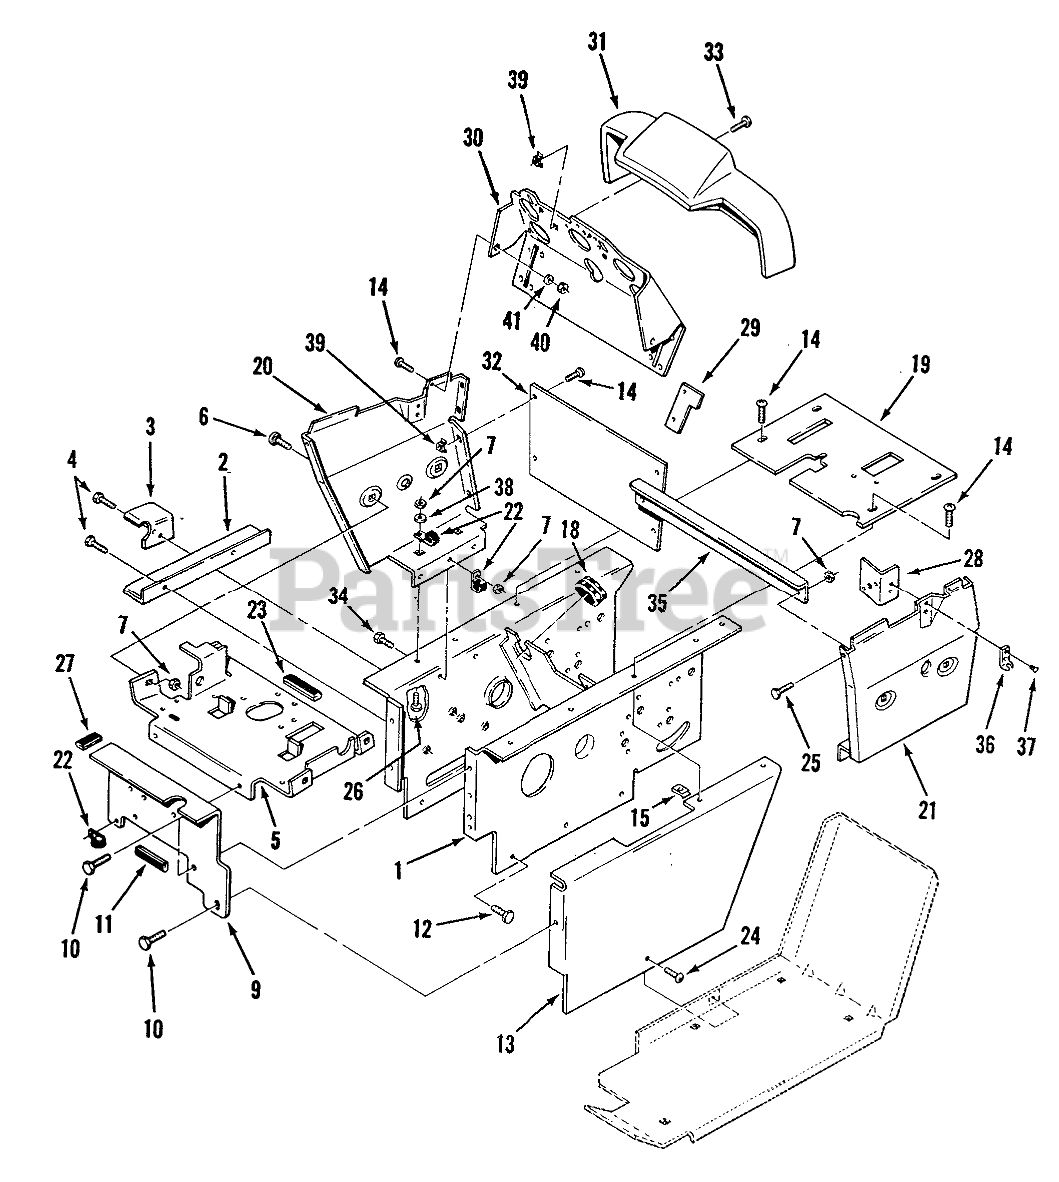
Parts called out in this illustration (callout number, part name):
1	Hoodstand
2	ANGLE-BELT GUARD B
3	BRCKET-BLT SUTB
4	SCREW
5	SUPPORT-BATTERY B
6	Bolt
7	Nut
9	PLATE-FRT HOODSTA B
10	SCREW
11	EDGE TRIM 2" 102896
12	SCREW
13	COVER-L.H. R
14	SCREW-PPH
18	GROMMET
19	Shift Cover Plate 520-H
20	Panel-RH
21	PANEL-SIDE LS B
22	CLIP
23	EDGE TRIM 5" OF 102896
24	Screw
24	WASHER 5/16 SAE
25	H H C S
26	CARRIAGE BOLT -4
27	DECAL-TACHAMATIC
28	BRACKET-SWITCH SU
29	STOP-CHOKE
30	PANEL ASSY OB
31	COVER-CONSOLE(3-G)
32	PLATE-HOODSTAND B
33	SCREW 1/4-20X.87
34	Bolt
35	STIFFENER-PANEL B
36	Latch Keeper (included in 106825 Hood Latch)
37	RIVET
38	WASHER 5/16 SAE
39	Nut 1/4-20
40	Nut
